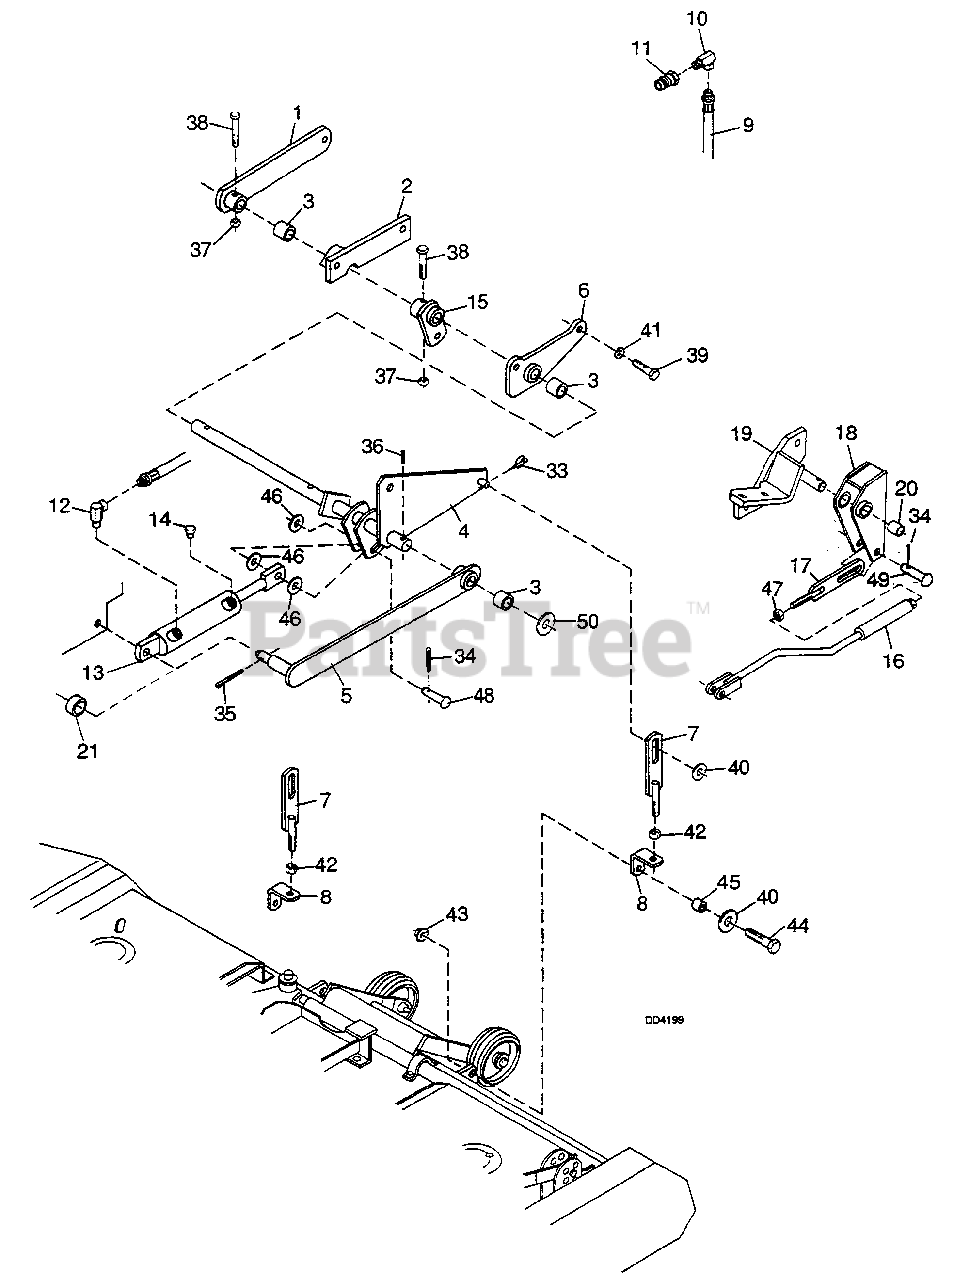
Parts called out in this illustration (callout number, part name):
1	Rear lift arm assembly
2	Right rear rockshaft assembly
3	1.015 x 1.25 x 1 Oilite bushing
4	Rear rockshaft assembly
5	Cylinder brace assembly
6	Left rear rockshaft assembly
7	Rear lift bar assembly
8	Lower lift link, 1/2-13
9	High-pressure hydraulic hose, 1/4 NPT x 65
10	1/2M x 1/4F 90° Swivel elbow
11	Coupler, Male 1/2 NPT
12	1/4 x 1/4 90° Swivel street elbow
13	Hydraulic cylinder
14	1/4 NPT Vent plug
15	Pull lug assembly, 2.5
16	Rear tie rod asy
17	Rear lift bar asy
18	Rear lift arm assembly
19	Lift mounting plate assembly
20	Bushing, 7/8 x 1 x 5/8
21	5/8 x 1-3/8 x 7/16 Washer
33	3/16 x 1 Klik pin
34	3/16 x 1 Cotter pin
35	3/16 x 2 Cotter pin
36	1/4 x 2 Spirol pin
37	10mm Hex locknut
38	10mm x 1.5P x 45mm Hex head cap screw
39	12mm x 1.75P x 30mm Hex head cap screw
40	1/2 Standard flat washer
41	1/2 Extra-heavy lockwasher
42	1/2 NC Hex jam nut
43	1/2 NC Flanged hex locknut
44	1/2 NC x 1-1/2 Hex head cap screw GR5
45	1/2 x 3/4 x 1/2 Sleeve
46	5/8 Standard SAE flat washer
47	5/8 NC Hex jam nut
48	5/8 x 1.65 Clevis pin
49	5/8 x 2-1/4 Clevis pin
50	1" SAE Flat washer
